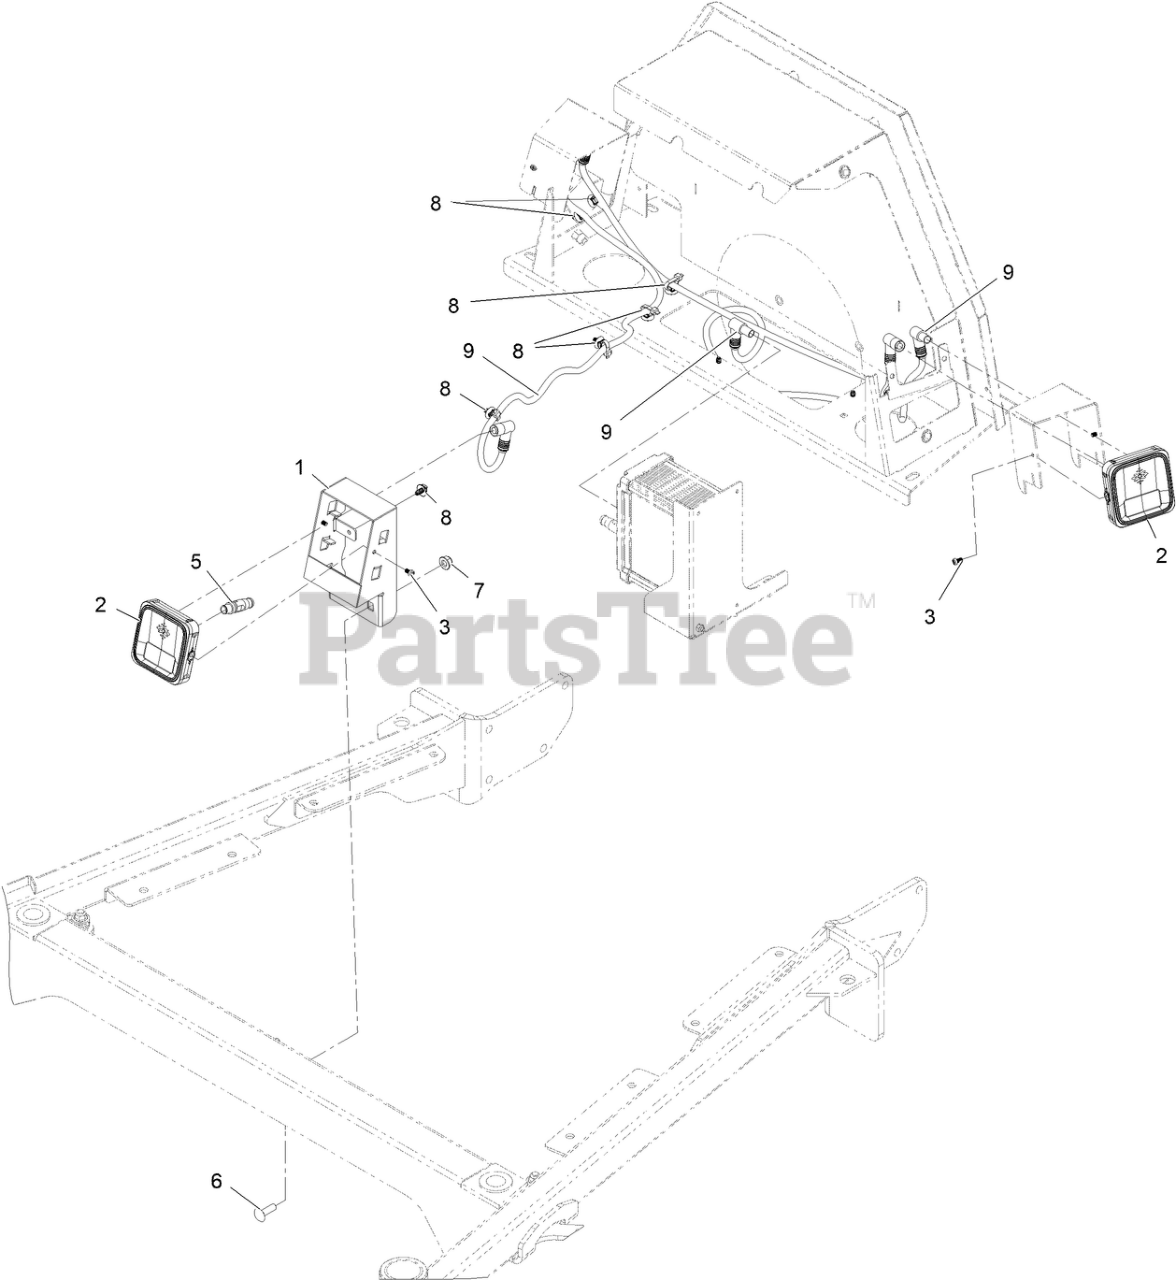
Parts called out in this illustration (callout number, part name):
1	BRACKET- RADAR
3	Screw-PPH
5	CABLE ASSY, ACS NOVA 2.1, RADAR PLUG
6	SCREW-CARR
7	NUT-HF, NI
8	CLIP-TIE, FIR TREE W/TIE, 5MM/.196"" HOLE
9	CABLE - RADAR SENSOR TO SENSOR
